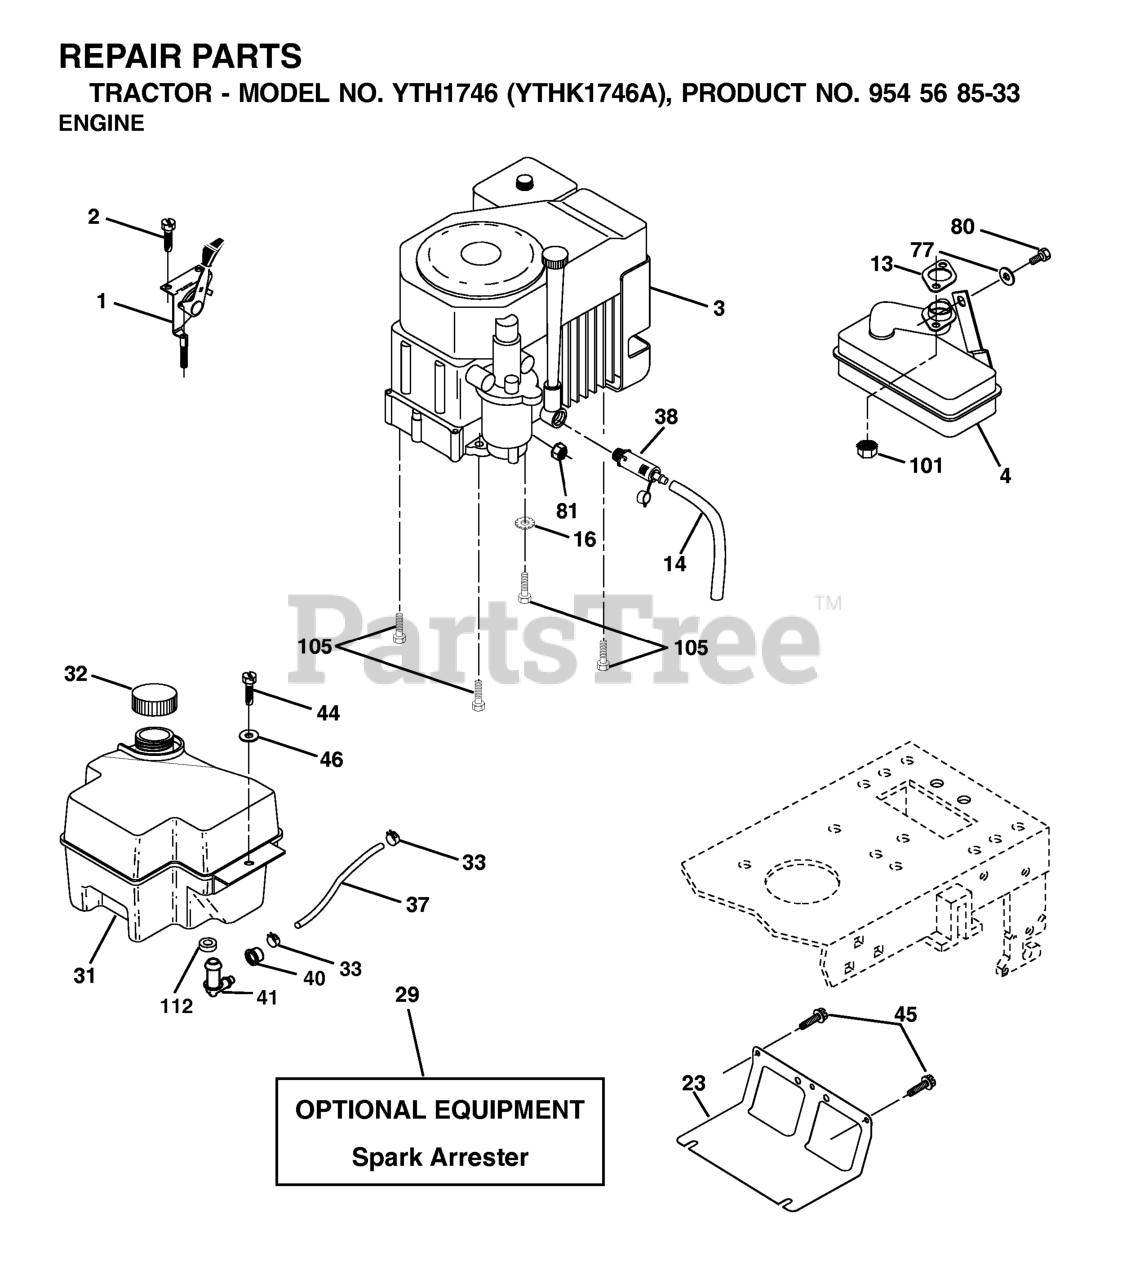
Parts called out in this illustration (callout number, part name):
1	CONTROL.THROTTLE.LT/YT
2	SCREW
4	MUFFLER.KOHL.CV491.W/PORT
14	TUBE, DRAIN OIL ASM.
16	LOCKWASHER
23	SHIELD.BROWNING.DBR.GUARD
29	KIT.SPARK ARRESTOR 794945 B&S
31	GAS TANK 2GAL
32	FUEL CAP
33	HOSE CLAMP
37	LINE.FUEL.20
38	PLUG, OIL DRAIN EASY
40	BUSHING.SNAP.NYL.BLK.
41	STEM FUEL TANK
44	SCREW HEXWSHR 1/4-20X3/4
45	SCREW, 3/8-16X3/4
77	WASHER
80	Bolt, Hex Head, Fin. 5/16-18 x 1/2
81	NUT
101	FLANGE NUT
105	SCREW 3/8-16X1
112	BUSHING OUTLET T
